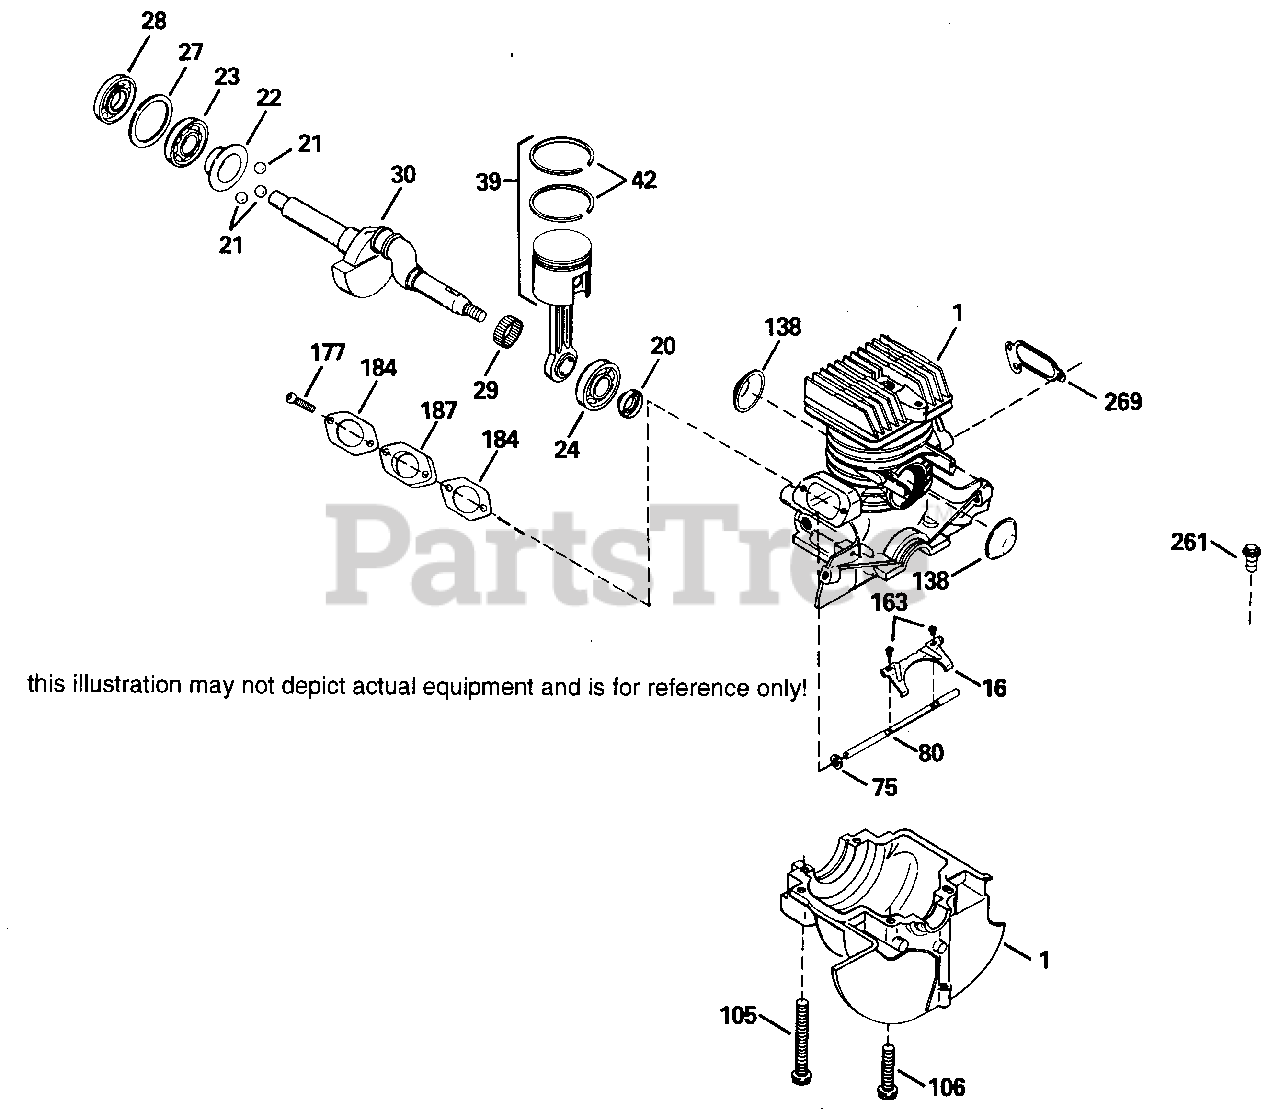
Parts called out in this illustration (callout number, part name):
1	"Cylinder Ass'y. (Incl. 75A, 138, 105, 106)6 & 138)
16	Lever, Governor
20	Seal (Flywheel end)
22	Ring, Slide
23	Bearing, Ball (PTO End)
24	Bearing, Ball (Magneto End)
27	Retainer, Bearing
28	Seal (PTO End)
29	Bearing Strip (31 needles)
30	Crankshaft
39	Piston & Rod Assy. (Incl. 29 & 42)
42	Ring Set, Piston
75	Seal, Oil
80	Shaft, Governor
105	Screw, 5/16-18 x 2-3/16"
106	Screw, 5/16-18 x 1-5/8"
138	Cover, Port
163	Screw, 4-40 x 1/4"
177	Screw, 5/32, 1/4-20 x 1"
184	Gasket, Carburetor
187	Spacer, Carburetor
261	Screw, 5/16-18 x 5/8"
269	Gasket, Muffler
